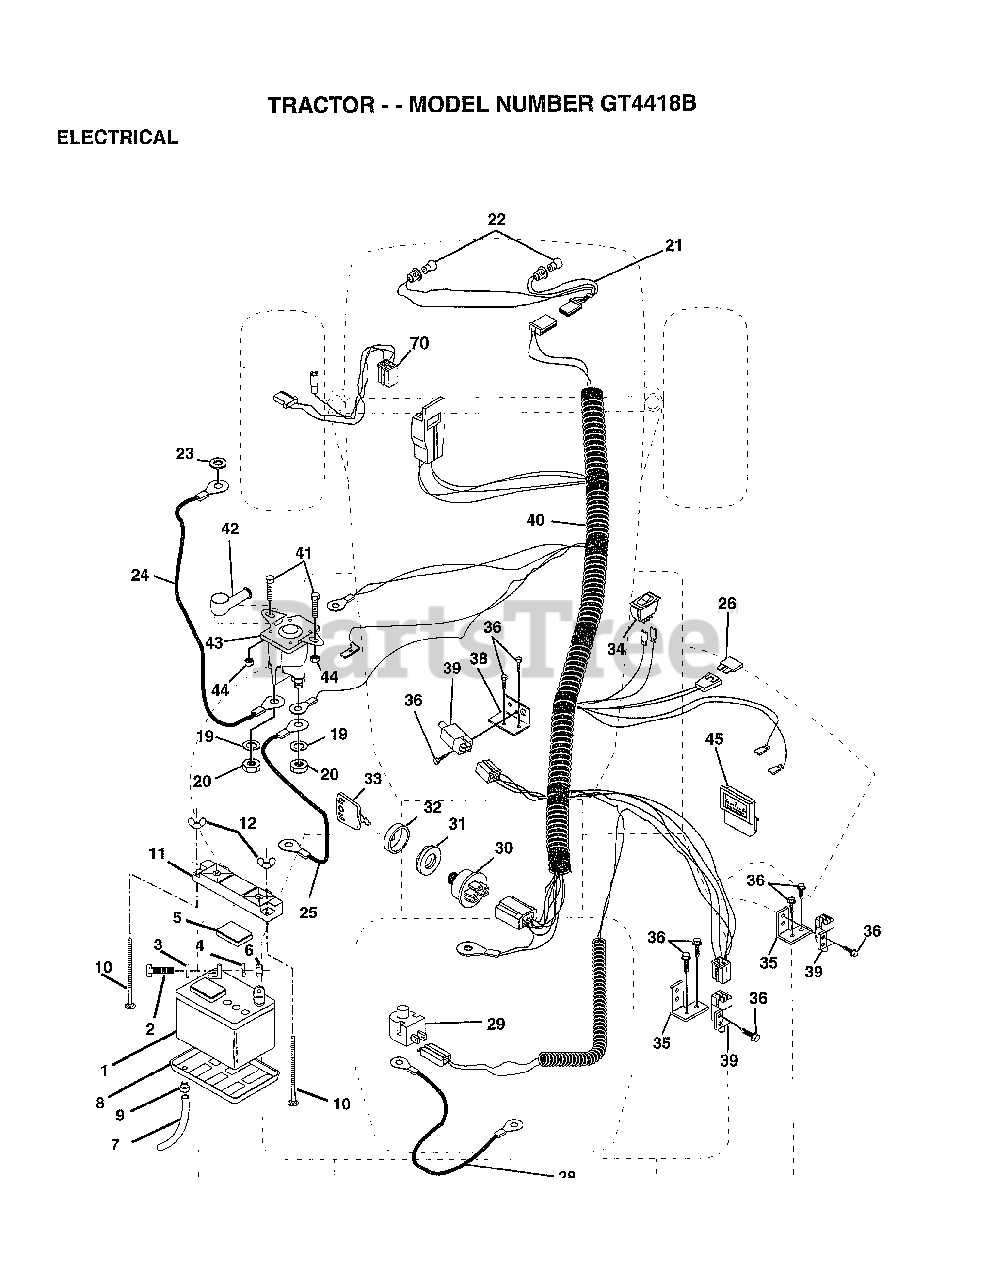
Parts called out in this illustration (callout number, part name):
2	BOLT LT
3	WASHER
4	LOCKWASHER
5	"CAP,BATTERY "
7	"DRAIN TU T, BATT"
8	"TRAY T, BATTERY"
9	HOSE CLAMP T
10	BOLT
20	NUT
21	"HARNESS,LIGHT SOC"
22	HEADLAMP BULB
23	LOCKWASHER
24	"CABLE T, BATTERY"
25	CABLE-BATTERY T
26	FUSE HYT
28	CABLE T
29	SWITCH SEAT
32	COVER KEY SWITCH
33	KEY MLD GEN DELTA
34	SWITCH LT
35	BRACKET LT
36	SCREW
38	BRACKET SWITCH IN
39	SWITCH INTERLOCKT
40	HARNESS IGNITION
41	BOLT HXHD FIN
44	NUT HXKEP 1/4X20
70	HARNESS ENGINE
